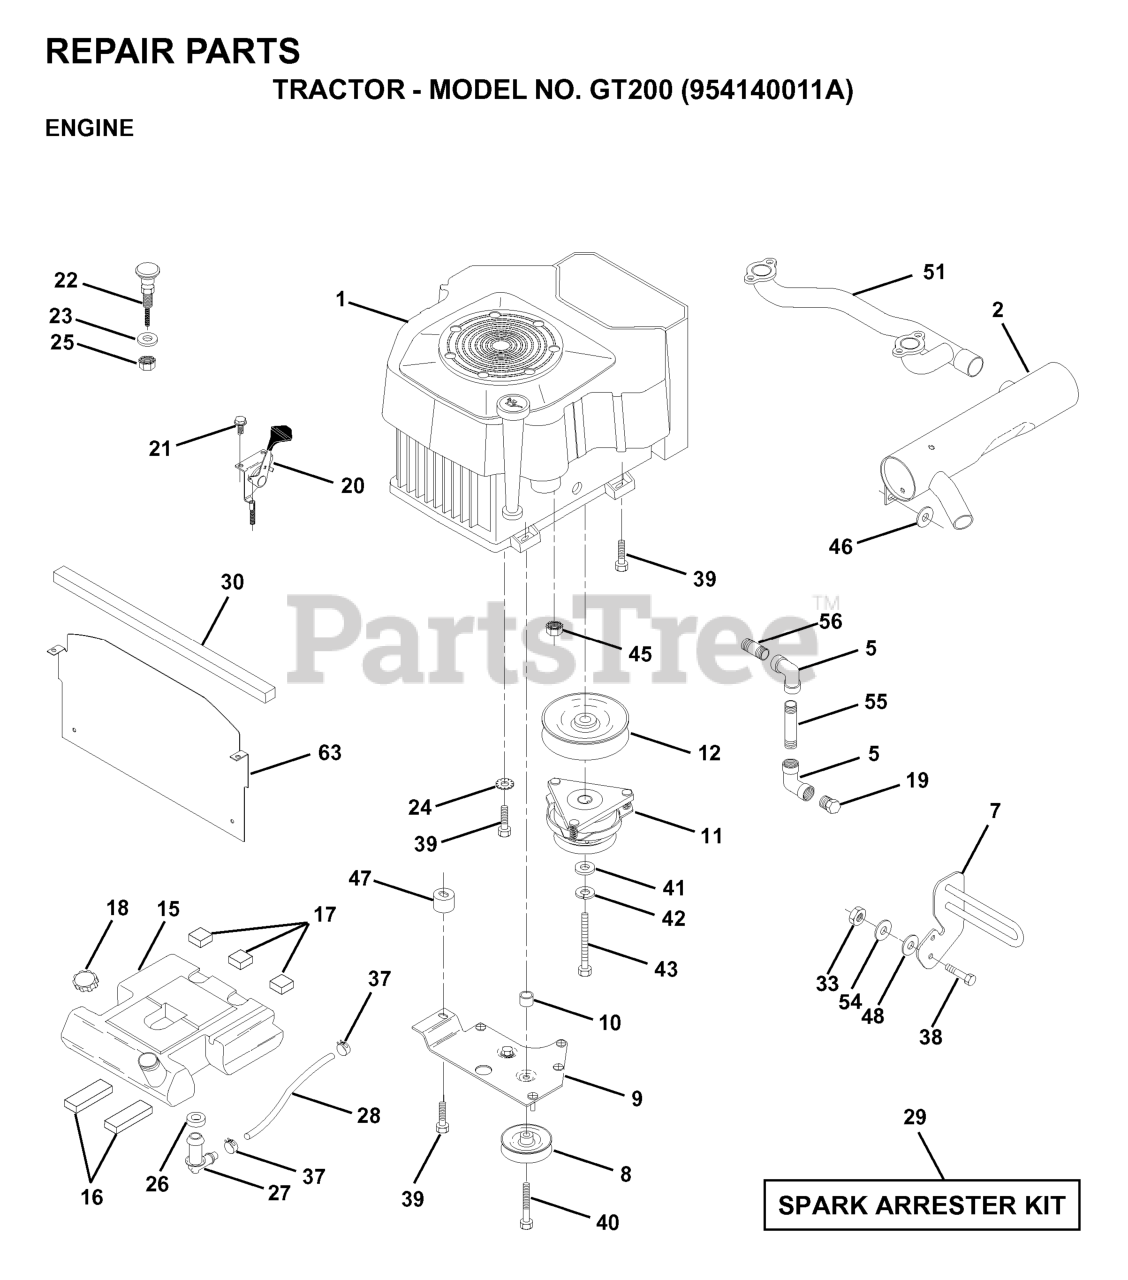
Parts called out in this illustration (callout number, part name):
2	MUFFLER VGT CYLINDER
5	ELBOW
8	RP.IDLER GROOVED
9	KEEPER ASM. BELT ENGINE VGT 96
11	CLUTCH ELECTRIC
12	PULLEY ENG VGT ELECT CLUTCH
15	FUEL TANK 3.5G
16	PAD IDLER TI
17	PAD-SPACER LT
18	FUEL CAP
20	THROTTLE CONTROL
21	SCREW LT
22	CHOKE CONTROL
23	WASHER
24	LOCKWASHER
25	Nut Keps 3/8 - 24 UNF
26	BUSHING OUTLET T
27	STEM FUEL TANK
28	HOSE
30	FOAM-STRIP LT
33	NUT
37	HOSE CLAMP
38	BOLT
39	SCREW TT 3/8-16X2-1/4 UNC
40	Screw TT 3/8-16 x 4 unc
42	LOCKWASHER
43	BOLT HEX
45	NUT FLANGE 1/4-20 STARTER NUT
46	WASHER
47	SPACER.ENGINE.CV22.ROUND.PM
48	Washer 13/32 x 1-1/4 x 7 Ga.
51	PIPE CROSSOVER
55	NIPPLE, PIPE 3/8NPT X 4-1/2
56	NIPPLE, PIPE 3/8 NPTX1.00
63	SHIELD, HEAT VGT YP/HUSQ
